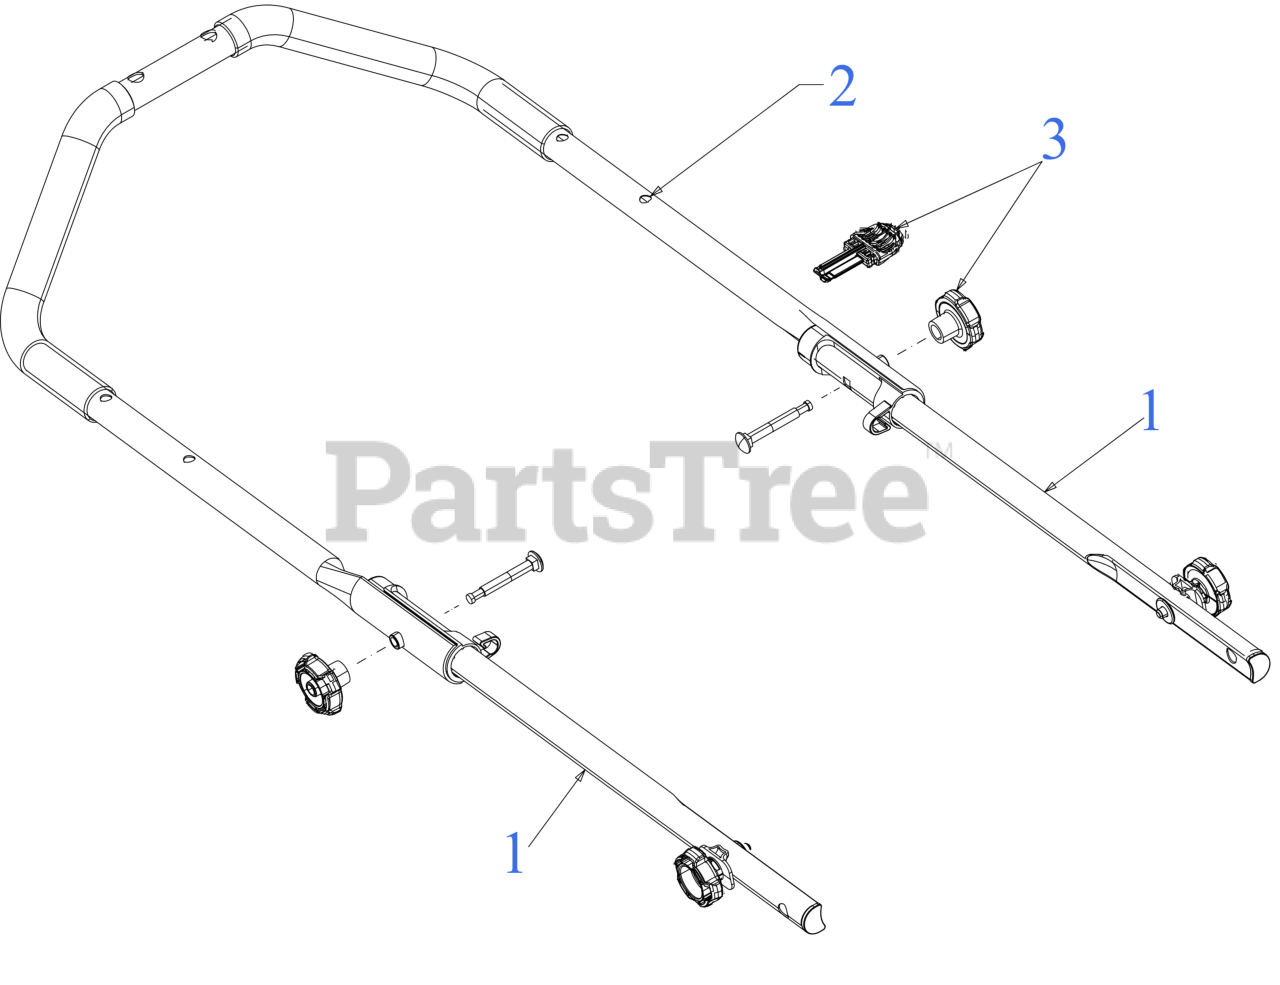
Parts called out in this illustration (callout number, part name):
1	HANDLE (LOWER)
2	HANDLE (UPPER)
3	HARDWARE KIT (KNOB/KEY) (BLACK)
